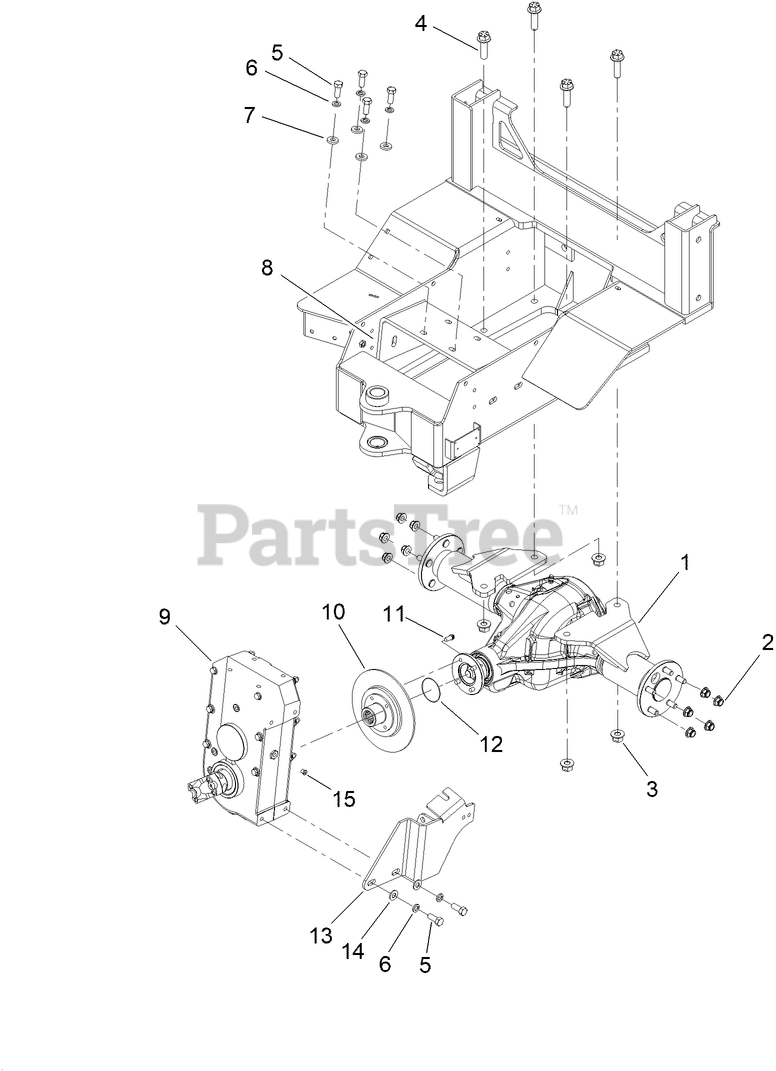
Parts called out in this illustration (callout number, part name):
1	DANA 44 ASSEMBLY
2	NUT-HHF
3	FLG LOCKNUT (5/8-NC, GR G)
5	SCREW-HH
6	WASHER-LOCK
7	WASHER-HARDENED
8	MOUNT-GEARBOX
9	TRANSMISSION ASM
10	FLANGE-COMPANION
11	SCREW-12 PT FLANGE
12	O-RING(-36), D70
13	BRAKE MOUNT
14	WASHER-FLAT
